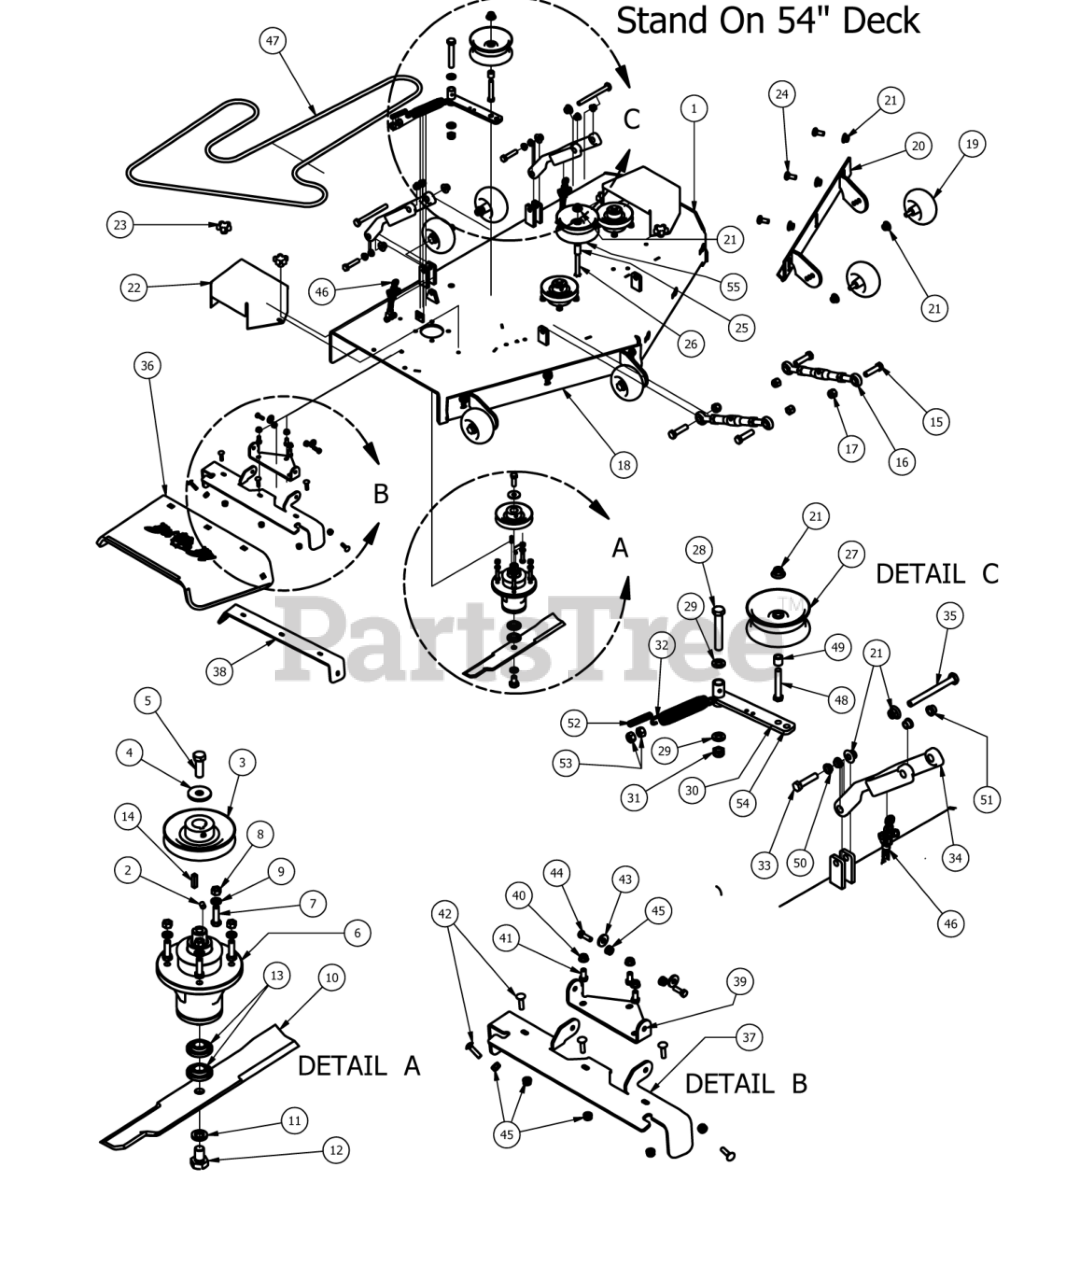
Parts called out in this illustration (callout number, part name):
1	54" Stand Up Deck
2	3/8" Set Screw
3	5" Deck Pulley
4	1/2 Belleville Washer
5	1/2"-20 x 1 1/2 - Grade 5 Fine Thread Bolt
6	Double Bearing Spindle
7	3/8" x 1 1/4" Hex Bolt
8	3/8-16 Hex Nuts Zinc
9	3/8" Lock Washer
10	54" Deck Fusion Blade For Outlaw
11	5/8" Lock Washer
12	5/8" x 1 1/2" Grade 8 Bolt
13	Double Bearing For Spindle
14	1/4" x 1" Key
15	5/8" x 2 1/2" Hex Bolt
16	Turnbuckle (Top Link)
17	5/8 Std NC Nylock Nut
18	54 Ou Adjustable Deck Front (left)
19	Deck Wheel
20	54 Outlaw Adjustable Deck Front (Right)
21	1/2-13 Nylon Flange Nut-Orange
22	Pulley Cover
23	5/16" Knob
24	1/2" x 1 1/4 Carriage Bolt
25	Pup Pulley Spacer
26	1/2 x 3 1/2 Flange Bolt Grade 8
27	5 3/4" Deck Idler Pulley
28	5/8" x 4" Hex Bolt
29	.635 ID Plastic Washer
30	Deck Idler 2009 AOS
31	5/8" Nylock (1/2 Jam)
32	2009 Deck/Pump Idler Spring
33	1/2-13X 2-1/4 GR Hex Bolts
34	Deck Arm Assembly
35	1/2" x 5 1/2" Bolt
36	Rubber Discharge Chute
37	Dischurge Chute Upper Hanger
38	60" Lower Hanger
39	Discharge Chute Hanger
40	3/8" Flange Nut
41	3/8" x 3/4" Hex Bolt
42	5/16" x 1 1/4" Carriage Bolt
43	.360 ID Plastic Washer
44	5/16" x 1" Bolt
45	5/16-18 Nylon Flange Nut
46	4- Link Adjustable Deck Hange
47	42" Deck Belt-B120
48	1/2-13 x GR 5 Hex Bolt Zinc
49	3/4 OD X 1/2 ID x 3\4 Length
50	Flange for Lower Deck Arm
51	Flange Bushing for Deck Arm Upper
52	All Thread-pump Idler Tensioner
53	1/2" Hex Nut
54	Deck Idler Assembly Components 21,27,30,48,49
55	5 3/4" Deck Idler Pulley
